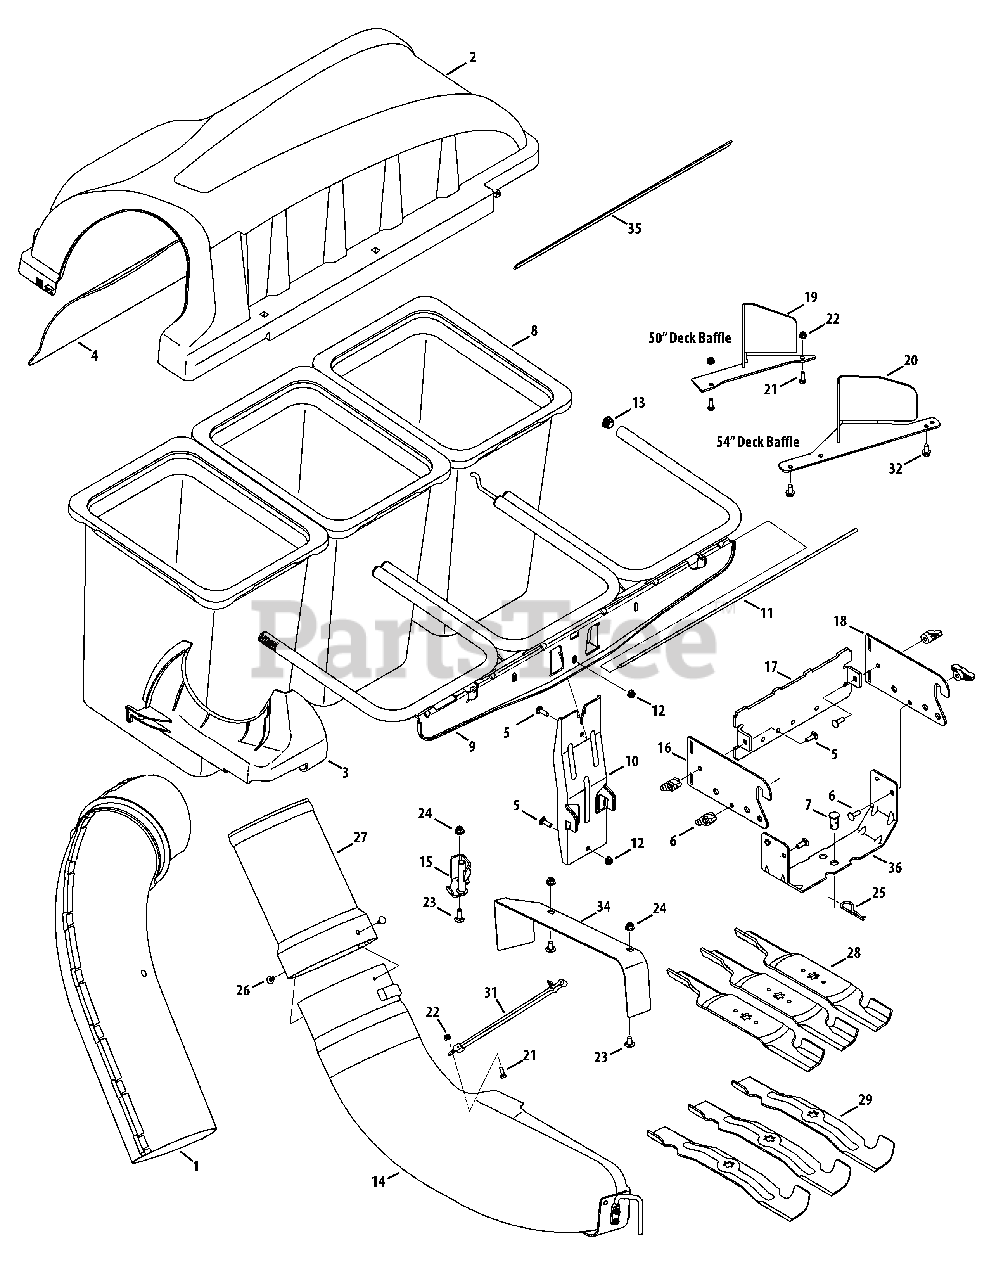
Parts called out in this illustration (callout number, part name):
1	Upper Chute Assembly
2	Triple Bagger Cover Assembly
3	Upper Chute Support
4	Bagger Cover Screen
5	Carriage Screw, 5/16-18 x 1.00"
6	Wing Knob, 5/16-18
6	Carriage Screw, 5/16-18 x 1.00"
7	Clevis Pin, .62" Dia.
8	Grass-bag Assembly
9	Triple Bag Support Assembly
10	Vertical Support Bracket
11	Cover Hinge Pin
12	Flange Lock Nut, 5/16-18
14	Discharge Chute Elbow, 50/54" Deck
15	Chute Stop-Bracket
16	Hitch Bracket, RH
17	Universal Rear Attachment Bracket
18	Hitch Bracket, LH
19	Deck Baffle, 50"
20	Deck Baffle, 54"
21	Tap Screw, 1/4 - 20 x .750 (50" Deck)
22	Flange Lock Nut, 1/4 - 20 (50" Deck)
23	Carriage Screw, 3/8 - 16 x 1.00"
24	Flange Lock Nut, 3/8 - 16
25	Internal Cotter Pin, .148 x 3.00
26	Ratchet Clip, .250
27	Bagger Chute Adapter, 7 In.
28	Blade, 18.50 Lg., High Lift
29	Blade, 17.90 Lg., Star Bagging
30	Universal Bracket Support
31	Chute Strap
32	Tap Screw, 5/16-18 x .750 (54" Deck)
34	Discharge Chute Plate
35	Adhesive Foam Strip
36	Hitch Support Bracket
